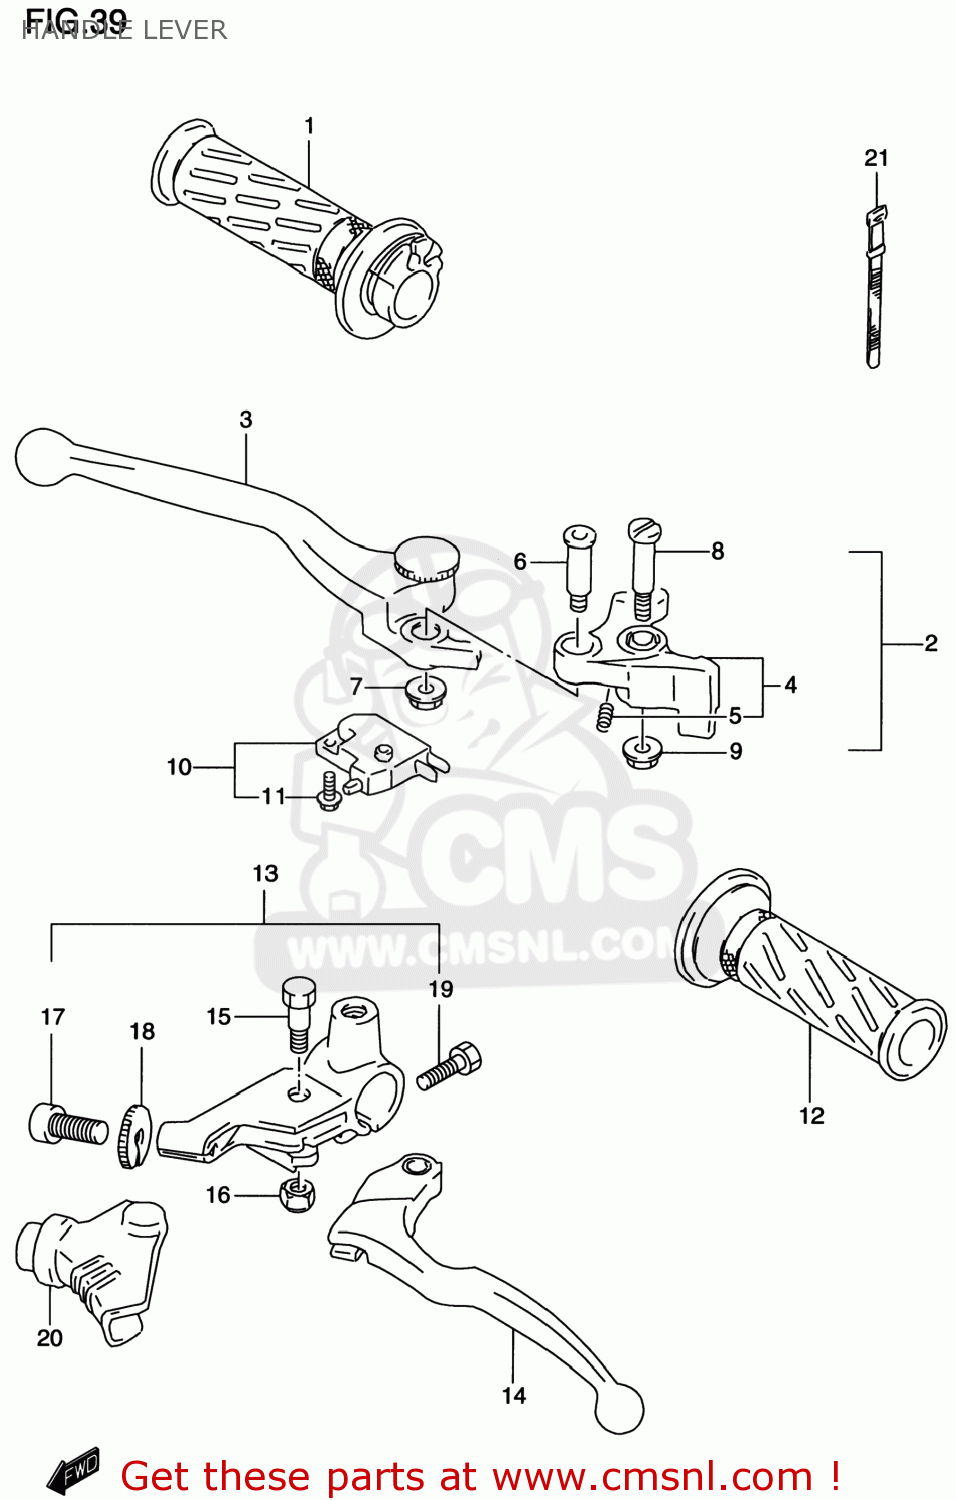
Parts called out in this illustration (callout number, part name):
1	GRIP,THROTTLE
2	LEVER ASSY,BRAKE
3	LEVER,ADJUST
4	KNOCKER
5	SPRING
6	BOLT,LEVER
7	NUT
8	BOLT,LEVER PIVOT
9	NUT
10	SWITCH ASSEMBLY,STOP
11	SCREW
12	GRIP,LEFT
13	LEVER ASSY,CLUTCH
14	LEVER,CLUTCH
15	BOLT,LEVER SET
16	NUT
17	ADJUSTER,CABLE
18	NUT,CABLE ADJUSTER
19	SCREW
20	COVER,CLUTCH LEVER
21	CLAMP(L:120)
